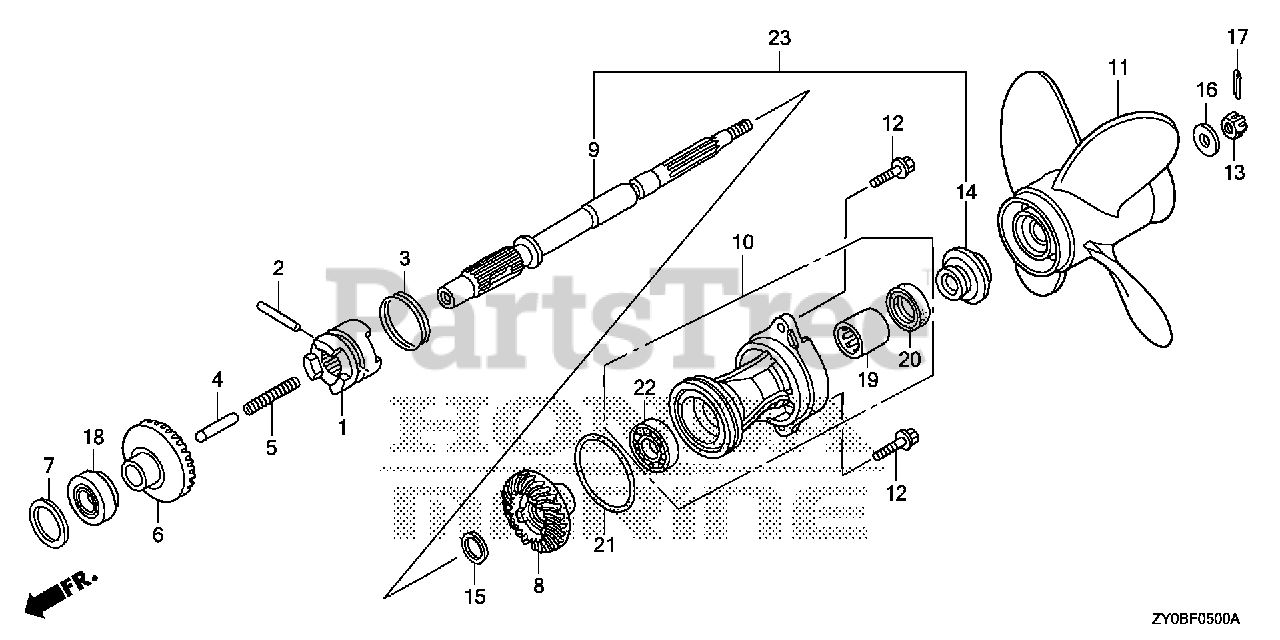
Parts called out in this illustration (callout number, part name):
1	SHIFTER, CLUTCH
2	ROLLER (4X29.8)
2	PIN, SHIFTER (4X30)
3	RING, CROSS PIN
4	SLIDER, SHIFT
5	SPRING, SHIFT
6	GEAR, FR. BEVEL
7	SHIM A (40MM)
7	SHIM B (40MM)
7	SHIM C (40MM)
7	SHIM D (40MM)
8	GEAR, RR. BEVEL
9	SHAFT KIT, PROPELLER
9	SHAFT, PROPELLER
10	HOLDER ASSY., PROPELLER SHAFT *NH282MU* (OYSTER SILVER METALLIC-U)
11	PROPELLER, FOUR BLADES (9-1/4X7) *NH283* (STIN GRAY)
11	PROPELLER, FOUR BLADES (9-1/4X8) *NH283* (STIN GRAY)
11	PROPELLER, FOUR BLADES (9-1/4X9) *NH283* (STIN GRAY)
11	PROPELLER, FOUR BLADES (9-1/4X10) *NH283* (STIN GRAY)
11	PROPELLER, FOUR BLADES (10X7-5/8) *NH283* (STIN GRAY)
12	BOLT, FLANGE (6X20)
13	NUT, CASTLE (10MM)
14	WASHER, PROPELLER THRUST
15	WASHER (18MM)
16	WASHER (10MM)
17	PIN, SPLIT (3MM)
18	BEARING (25X47X15)
19	BEARING, NEEDLE (17X24X20) (NTN)
20	SEAL, WATER (17MM)
21	O-RING (59.4X3.1)
22	BEARING, RADIAL BALL (25X47X12)
22	BEARING, RADIAL BALL (6005)
23	SHAFT KIT, PROPELLER
